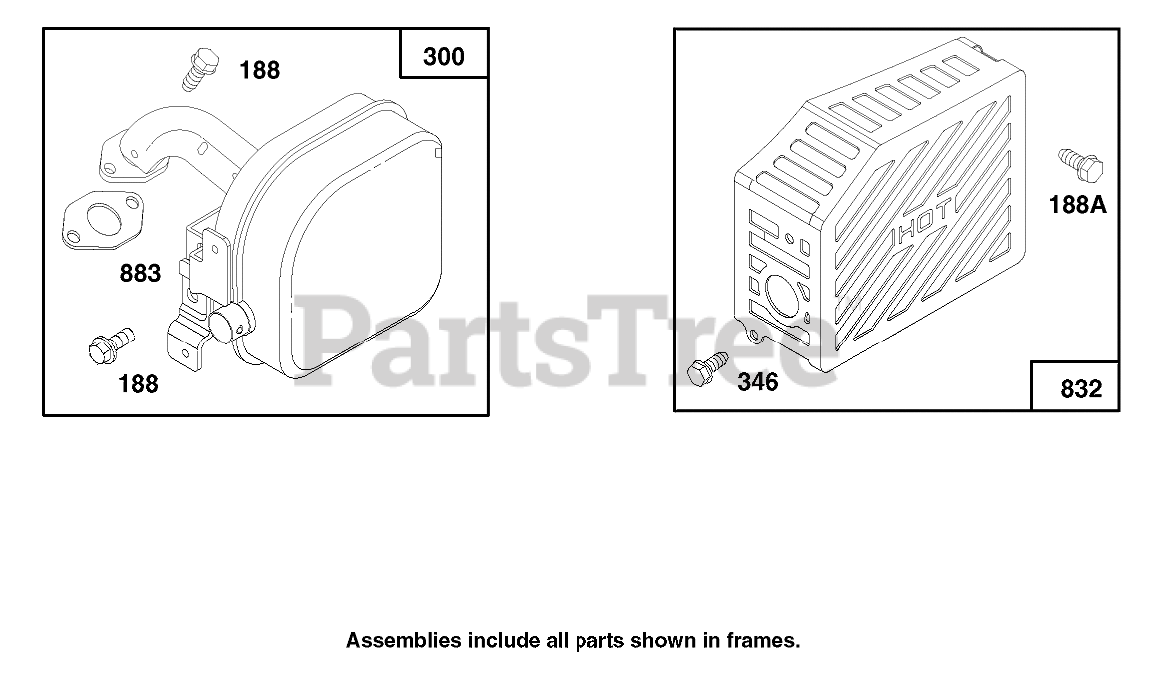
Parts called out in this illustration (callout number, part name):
188	Screw-Cap
188A	SCREW - HEX HEAD
300	MUFFLER - EXHAUST
346	Screw-Hex
832	Guard-Muffler
883	EXHAUST GASKET
